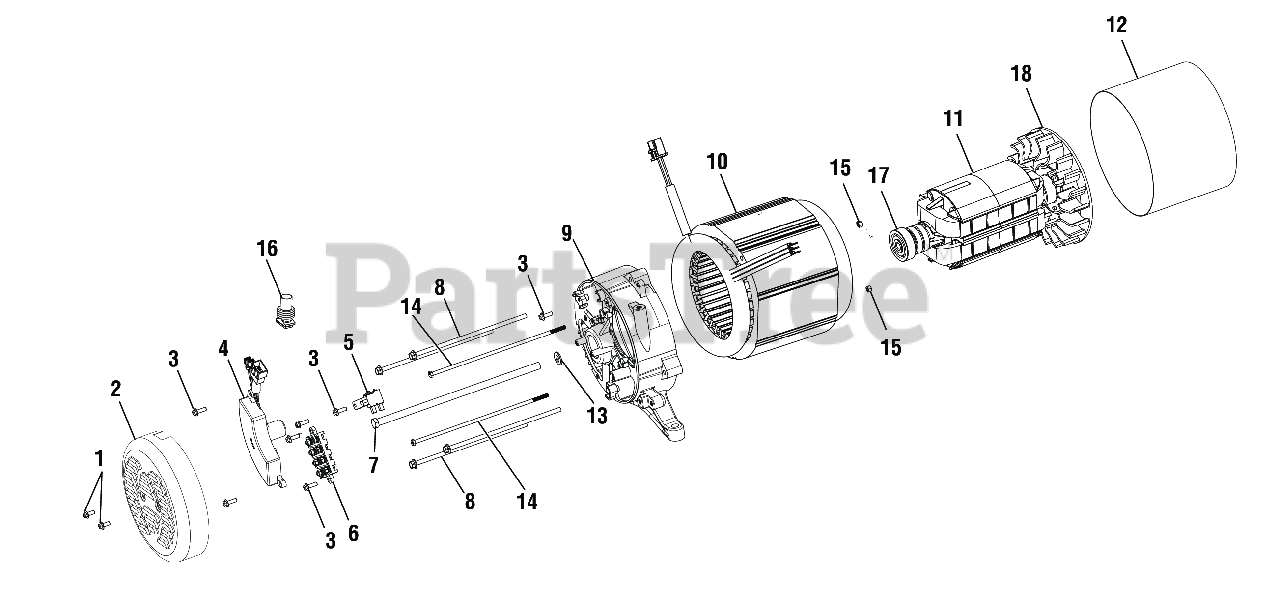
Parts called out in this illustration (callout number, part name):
1	Bolt (M5 x 12 mm, Hex Flange Hd.)
2	Engine Cover
3	Bolt (M5 x 16 mm, Hex Flange Hd.)
4	Automatic Voltage Regulator
5	Brush Assembly Kit
6	Terminal Block Assembly
7	Rotor Bolt (M10 x 272 mm, Hex Hd.)
8	Bolt (M6 x 187 mm, Flange Hex Hd.)
9	Bearing Support
12	Stator Band (139 mm)
13	Washer (ID8.4 x OD25.1 x 3t)
14	Bolt (M6 x 224 mm, Hex Hd.)
15	Hex Nut (M5)
16	Rubber Sleeve
17	Ball Bearing (190 mm)
